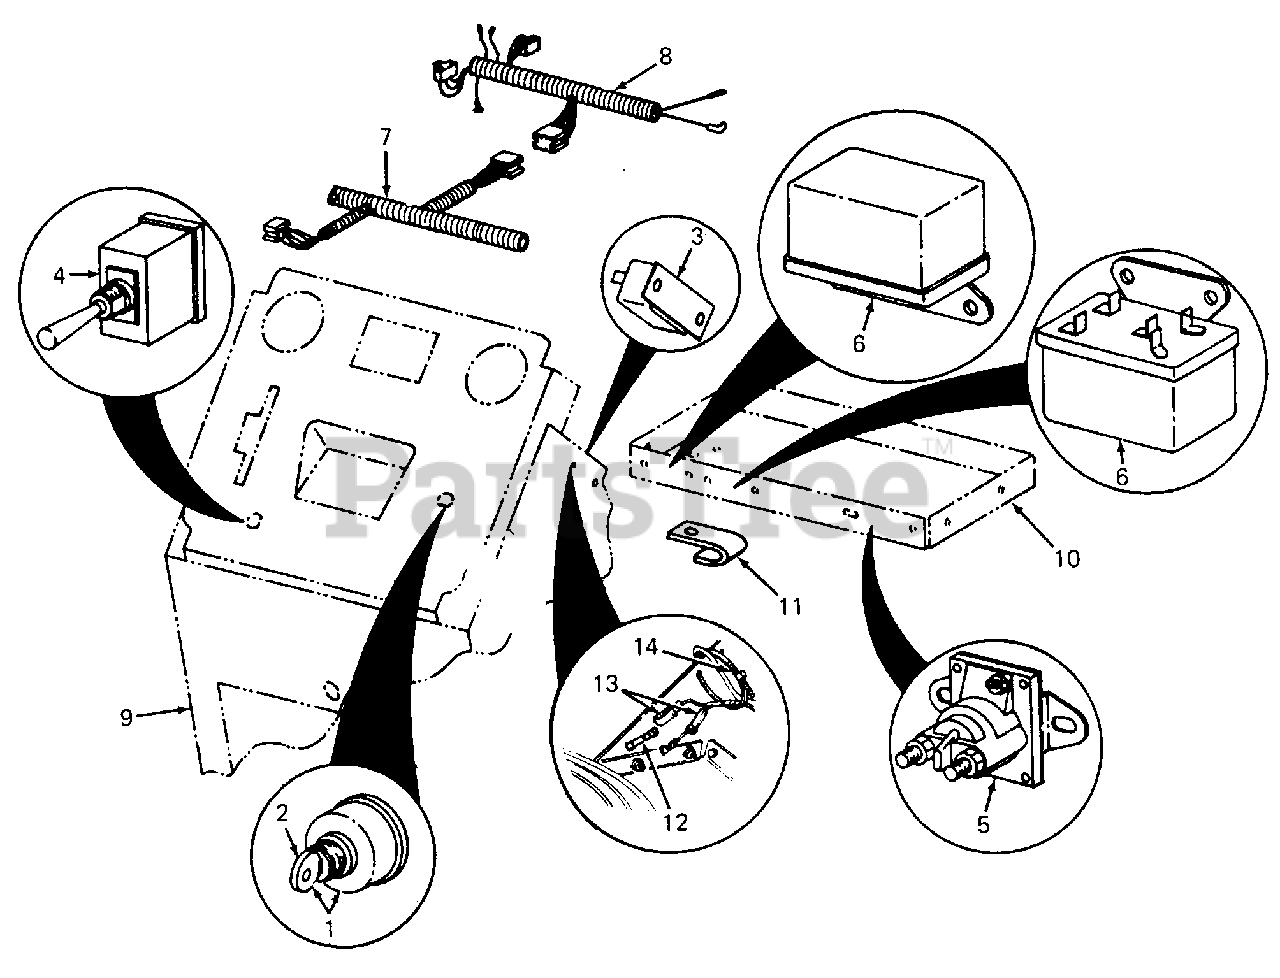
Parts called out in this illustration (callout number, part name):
1	Switch, Key
2	Key, Ignition (Set of 2)
3	Breaker, Circuit
4	Switch, PTO
5	Switch, Solenoid
6	Relay
7	Harness, Battery Tray
8	Harness, Main Wiring
10	Tray, Battery
11	Clip, Cable
12	Fuse
13	Fuse Holder
14	Cable Tie
